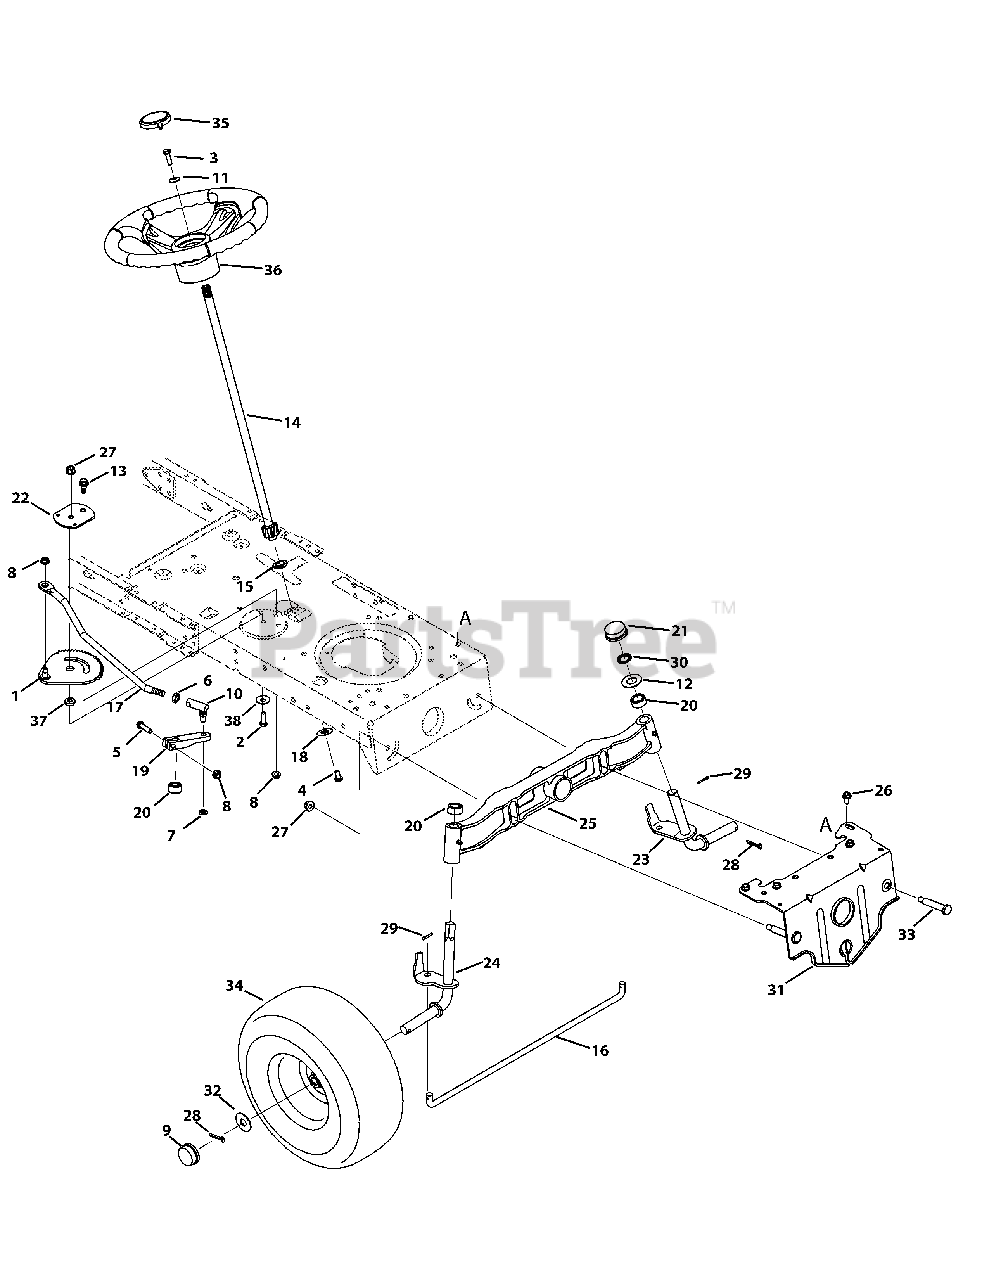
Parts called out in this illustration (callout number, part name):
1	Front Steering Gear Assembly
2	Hex Screw, 3/8-16 x 1.00
3	Screw, 5/16-18, 1.00, Gr5, Lock
4	Screw, Mach, 5/16-18, 0.750
5	Screw, 5/16-18, 1.75, Gr5
6	Nut, Jam, 7/16-20, Gr2
7	Nut, Hex Lock, 3/8-24
8	Nut, Flange Lock, 5/16-18, Grf
10	Ball Joint, 7/16-20, Lock
11	Washer, Bell, .340 x .872 x .060
12	Washer, Flat, .78 x 1.59 x .60
13	Shoulder Screw, .435 x .3485, 5/16-18
14	Steering Shaft, 5/8
15	Bearing, Flange, Hex 5/8
17	Steering Link
18	Cap, 1.25 x .16
19	Steering Block
20	Spacer, .710 ID x .125 OD x .56
21	Push Cap, Cast
22	Stabilizer Plate
23	Axle Assembly, LH
24	Axle Assembly, RH
25	Pivot Bar, Cast
26	Screw, 5/16-18, 0.750
27	Flangelock Nut, 3/8-16
28	Cotter Pin, 5/32 x 1.25
29	Pin, Cotter, 1/8 x 0.75
30	Push Nut 3/4 Dia.
31	Pivot Bar Bracket
32	Washer, Flat, .781 x 1.59
33	Scr., Shlder, .500 x 2.380, 3/8-16
34	Wheel Ass’y, Sq. Shldr., 15 x 6 x 6
35	Cap, Troy-Bilt
36	Steering Wheel
37	Spacer, .38 ID x .854 OD x .220
38	Bell Washer, .390 x 1.13 x .062
